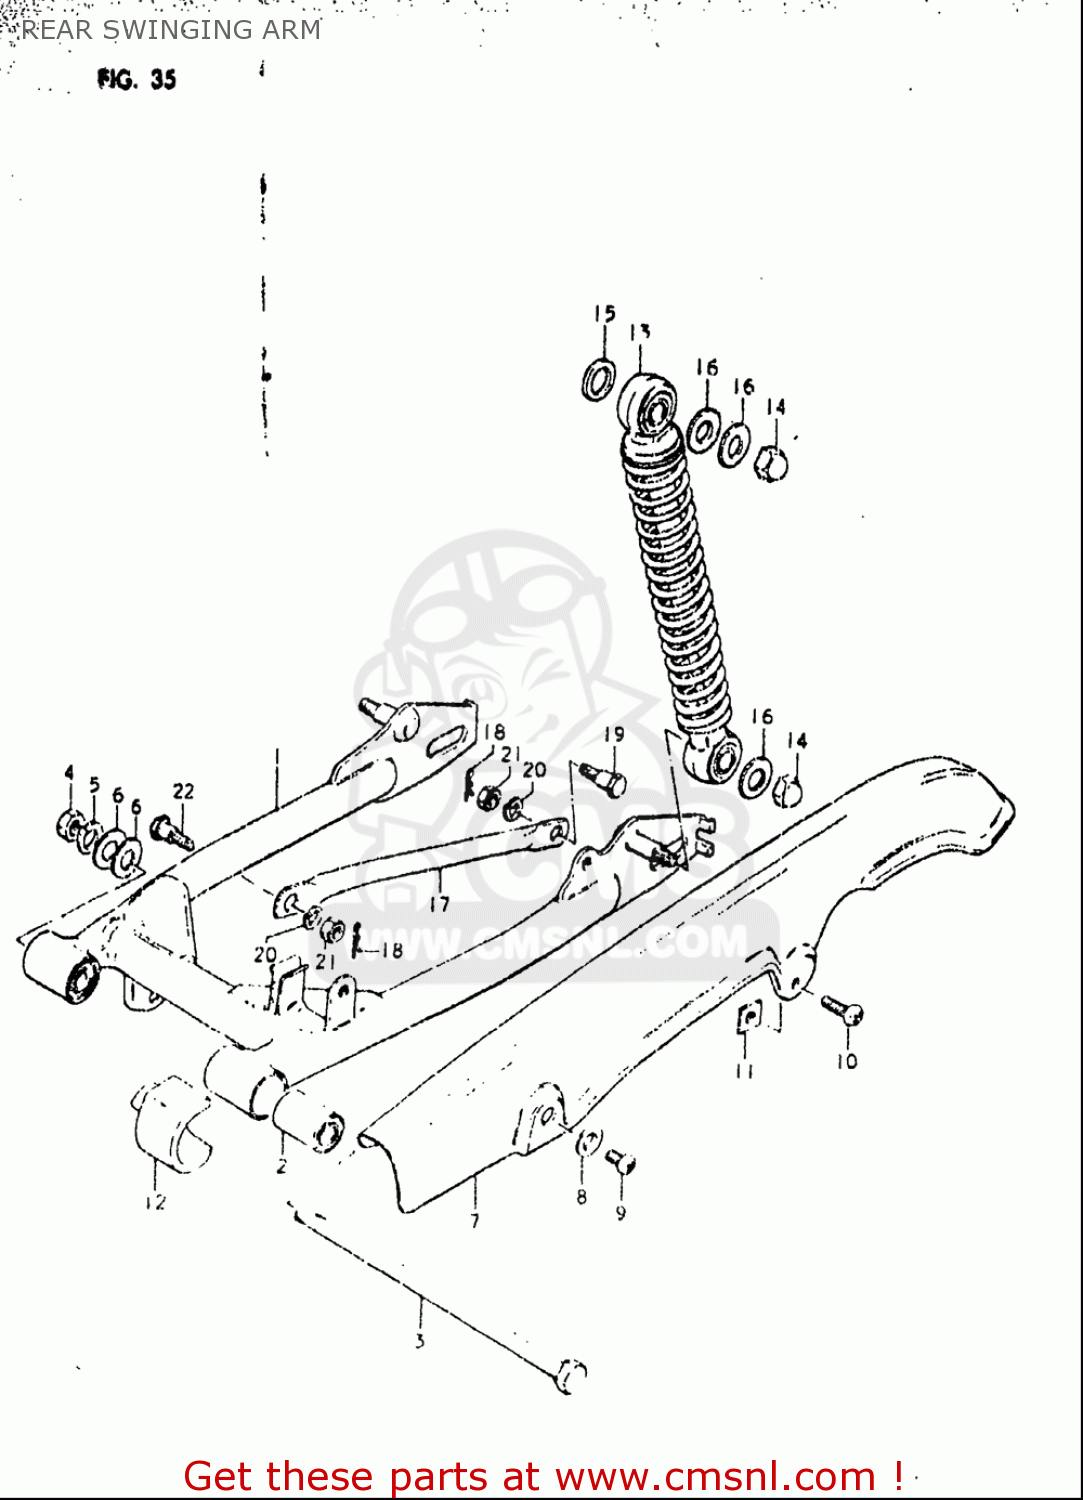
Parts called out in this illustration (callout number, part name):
2	BUSH
3	SHAFT,RR SHOCK ABSORBER UPR
4	NUT
5	WASHER,LOCK
6	WASHER
8	WASHER
9	SCREW
10	SCREW
11	NUT,CHAIN CASE RR
12	BUFFER,CHAIN TOUCH DEFENSE
14	NUT
15	WASHER
16	WASHER (10.5X24X2.3)
18	PIN
19	BOLT(8X26.5)
20	WASHER,LOCK
21	NUT
22	BOLT(8X22)
